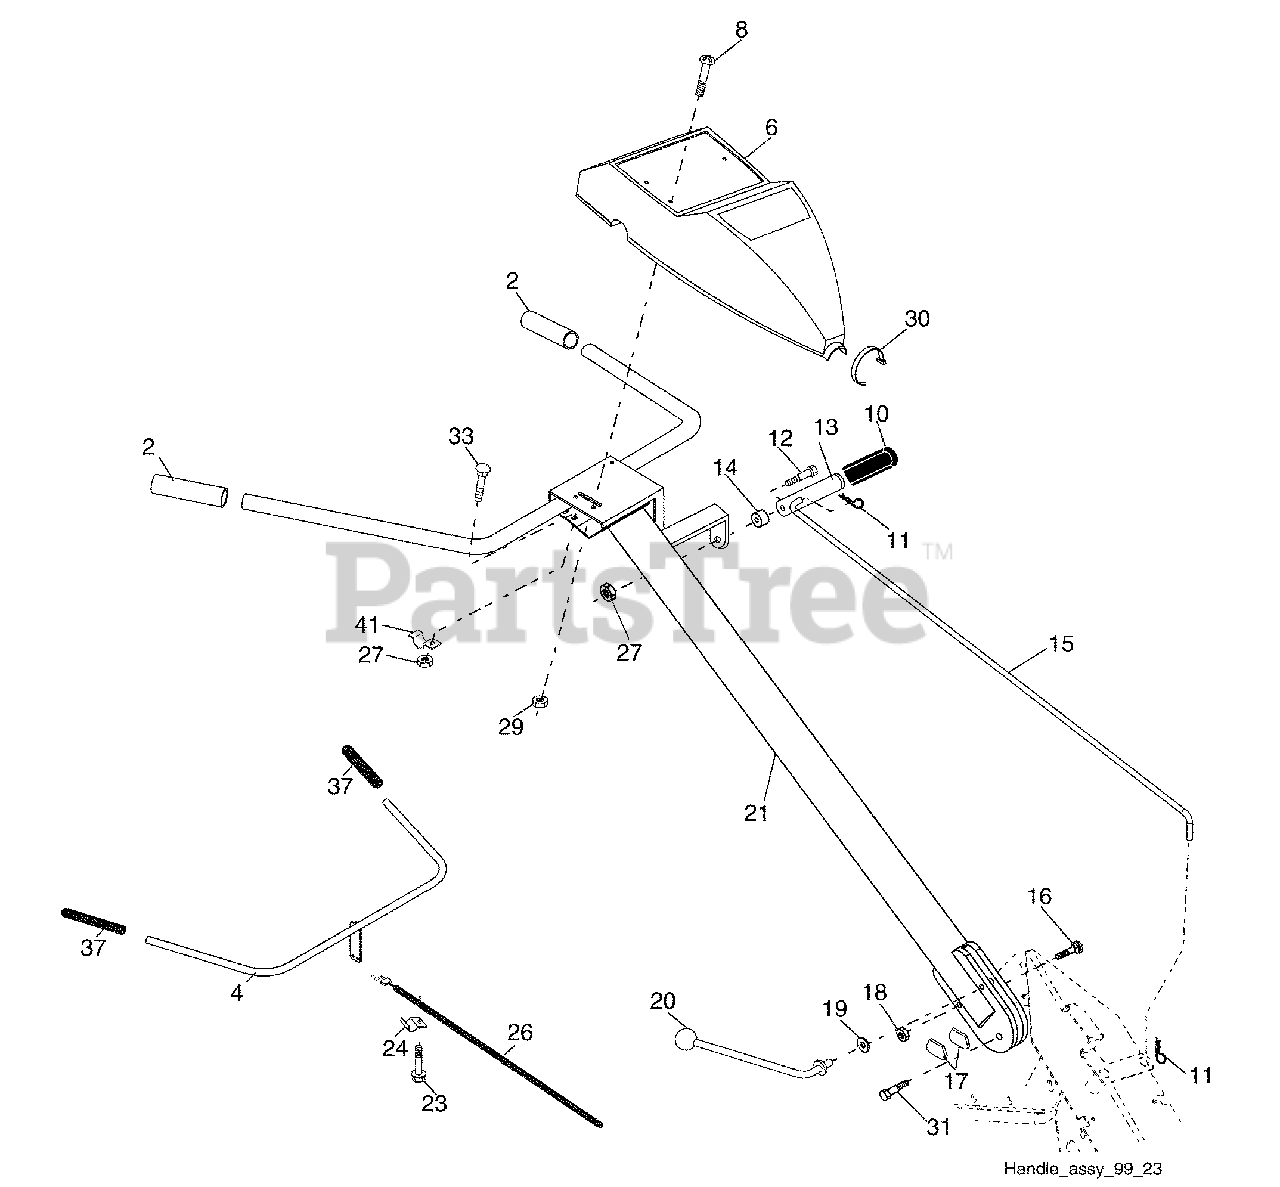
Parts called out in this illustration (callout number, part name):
1	Grip, Handle
2	Bar Assembly, Control
3	Panel, Control
4	Screw, Truss Hd. #10-24 unc x 1/2
5	Grip, Handle
6	Clip, Hairpin
7	Bolt, Shoulder
8	Handle, Shift
9	Grommet, Rubber
10	Rod, Shift
11	Bolt, Carriage 3/8-16 x 1 Gr. 5
12	Lock, Handle
13	Nut, Crownlock 3/8-16 unc
14	Washer 13/32 x 1 x 11 Ga.
15	Lever, Lock, Handle
16	Handle
17	Screw, Hex Washer SLT #10-24 x .50
19	Cable, Clutch
20	Nut, Hex Flange 1/4-20 unc
21	Nut, Keps #10-24 unc
22	Tie, Cable
23	Bolt, Pivot
24	Bolt, Carriage 1/4-20 unc x 1/2
25	Grip, Bar, Control
26	Clamp, Bar, Control
